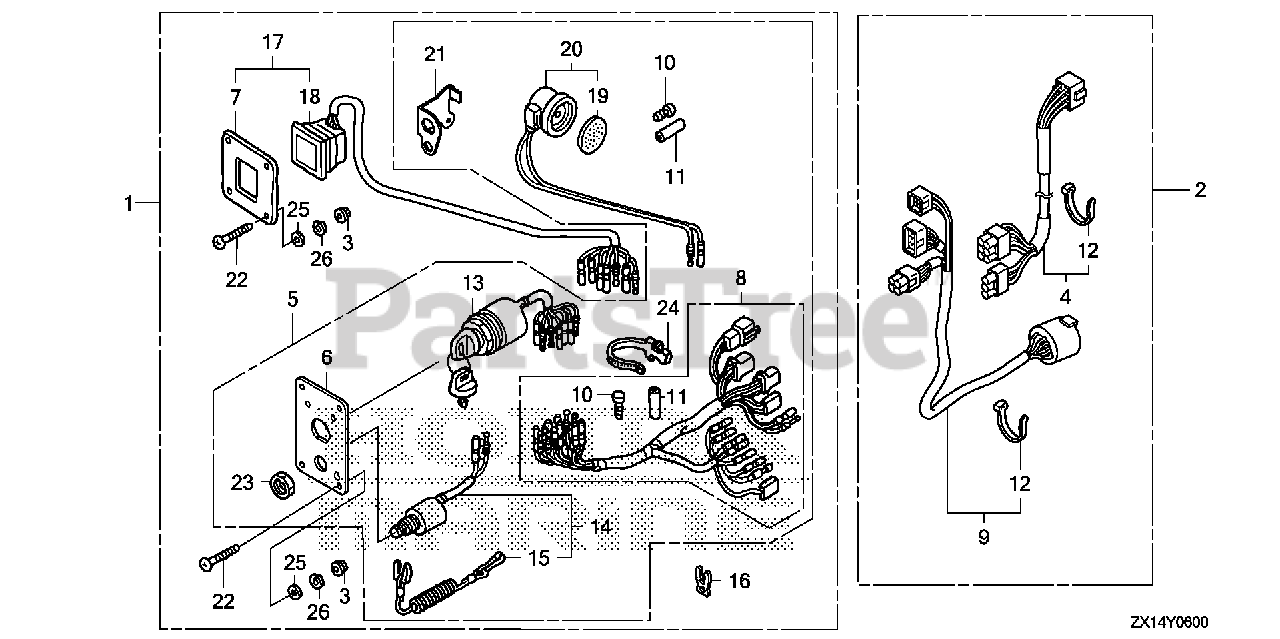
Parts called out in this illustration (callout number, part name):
1	PANEL KIT, SWITCH (4-LED) (B)
2	CABLE SET, PANEL INDICATOR (20FT)
2	CABLE SET, PANEL INDICATOR (25FT)
2	CABLE SET, PANEL INDICATOR (30FT)
3	NUT, FLANGE (5MM)
4	WIRE ASSY., INDICATOR (20FT)
4	WIRE ASSY., INDICATOR (25FT)
4	WIRE ASSY., INDICATOR (30FT)
5	PANEL ASSY., SWITCH
6	PANEL, CONTROL
7	PANEL, CONTROL
8	HARNESS ASSY., SWITCH PANEL
9	CABLE ASSY., SWITCH PANEL (25FT) (NHK MEC)
9	CABLE ASSY., SWITCH PANEL (20FT)
9	CABLE ASSY., SWITCH PANEL (25FT)
9	CABLE ASSY., SWITCH PANEL (30FT)
10	PLUG, CONNECTOR (INNER)
11	PLUG, CONNECTOR (OUTER)
12	TIE, CABLE (2.4X92) (NATURAL)
13	SWITCH ASSY., COMBINATION
14	SWITCH ASSY., EMERGENCY STOP
15	WIRE, EMERGENCY
16	CLIP, EMERGENCY LOCK
17	PANEL ASSY., INDICATOR (4-LED)
18	LAMP ASSY., INDICATION (4-LED)
19	PLATE, TURN SIGNAL BUZZER
20	BUZZER, WARNING
21	BRACKET, BUZZER
22	SCREW, PAN (5X40)
23	NUT, HEX. (16MM)
24	BAND, WIRE HARNESS (150MM) (NATURAL)
25	WASHER, PLAIN (5MM)
26	WASHER, SPRING (5MM)
